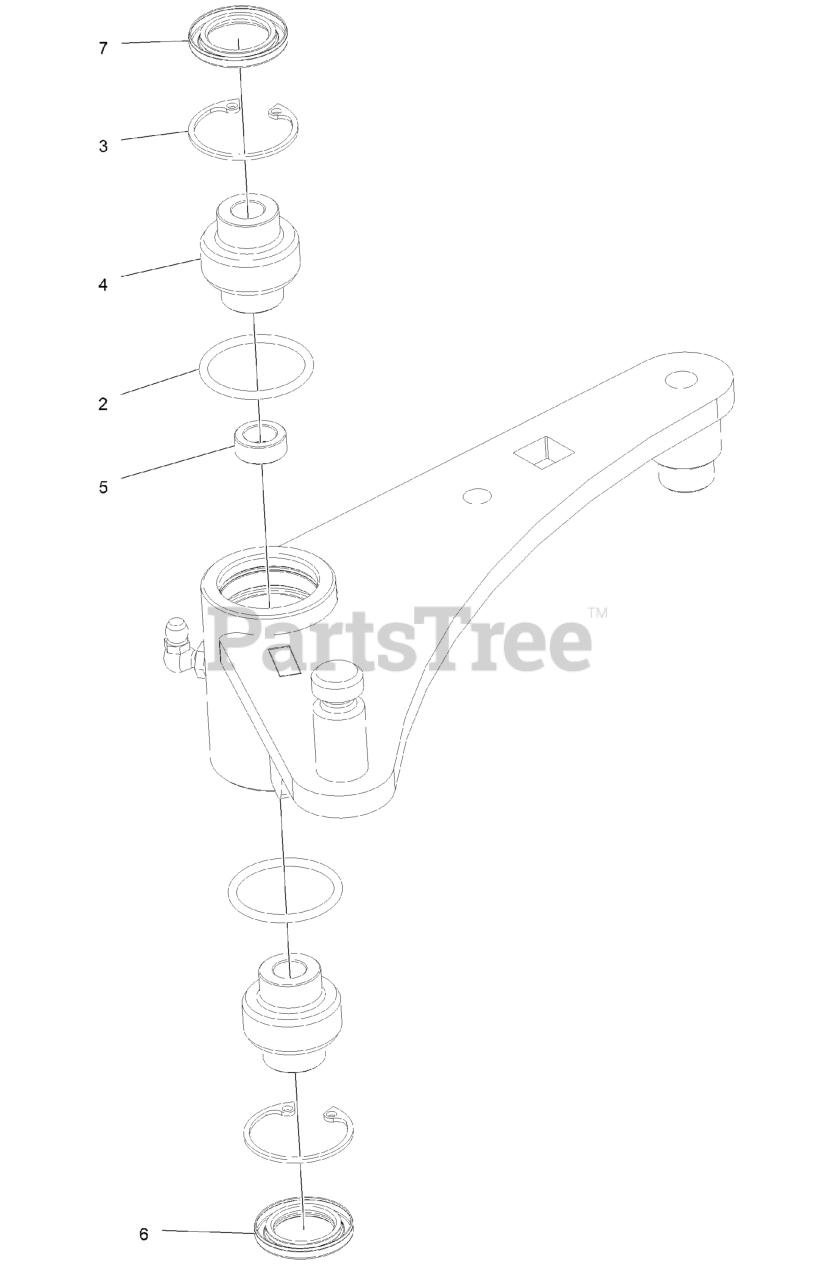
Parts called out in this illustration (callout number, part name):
3	RING-SNAP
4	BEARING-SPHERICAL
6	SEAL-LIP, DOUBLE
7	SEAL-LIP, SINGLE
